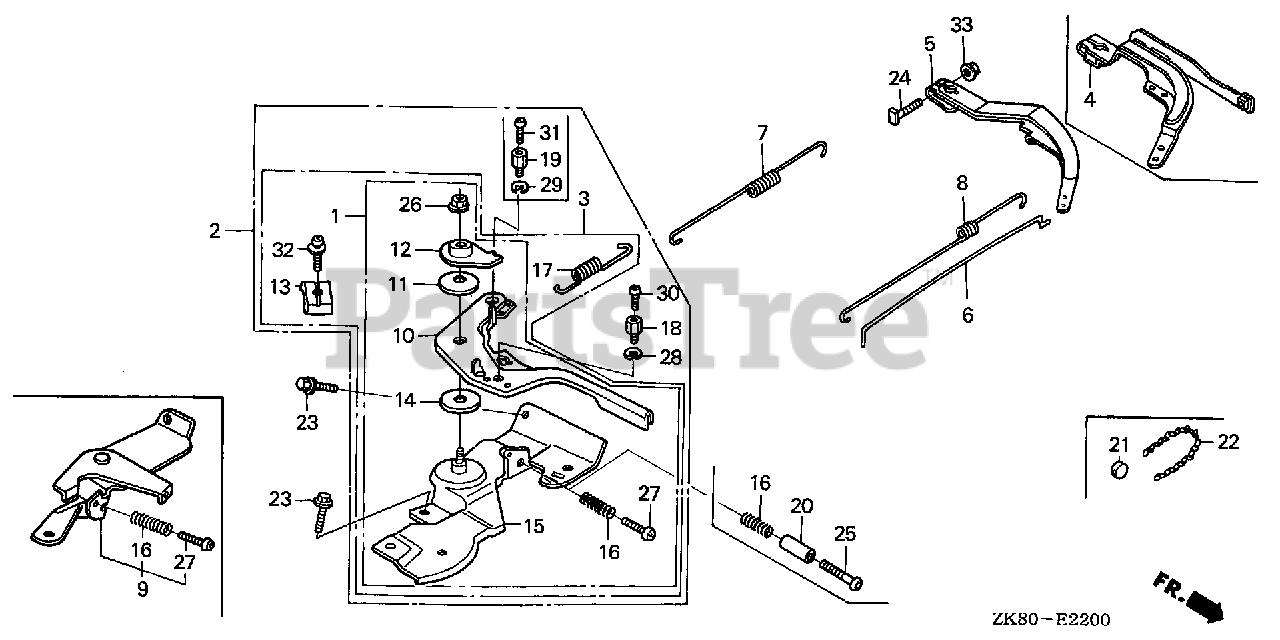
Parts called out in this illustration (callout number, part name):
3	CONTROL ASSY. (REMOTE)
5	ARM, GOVERNOR
6	ROD, GOVERNOR
7	SPRING, GOVERNOR
8	SPRING, THROTTLE RETURN
10	LEVER, CONTROL
11	SPRING, LEVER
12	WASHER, CONTROL LEVER
13	HOLDER, CABLE
14	SPACER, CONTROL LEVER
15	BASE, CONTROL (REMOTE)
16	SPRING, CONTROL ADJUSTING
17	SPRING, CABLE RETURN
23	BOLT, FLANGE (6X12) (CT200)
24	BOLT, GOVERNOR ARM
26	NUT, SELF-LOCK (6MM)
27	SCREW, PAN (5X25)
32	SCREW, PAN (5X16)
33	NUT, FLANGE (6MM)
